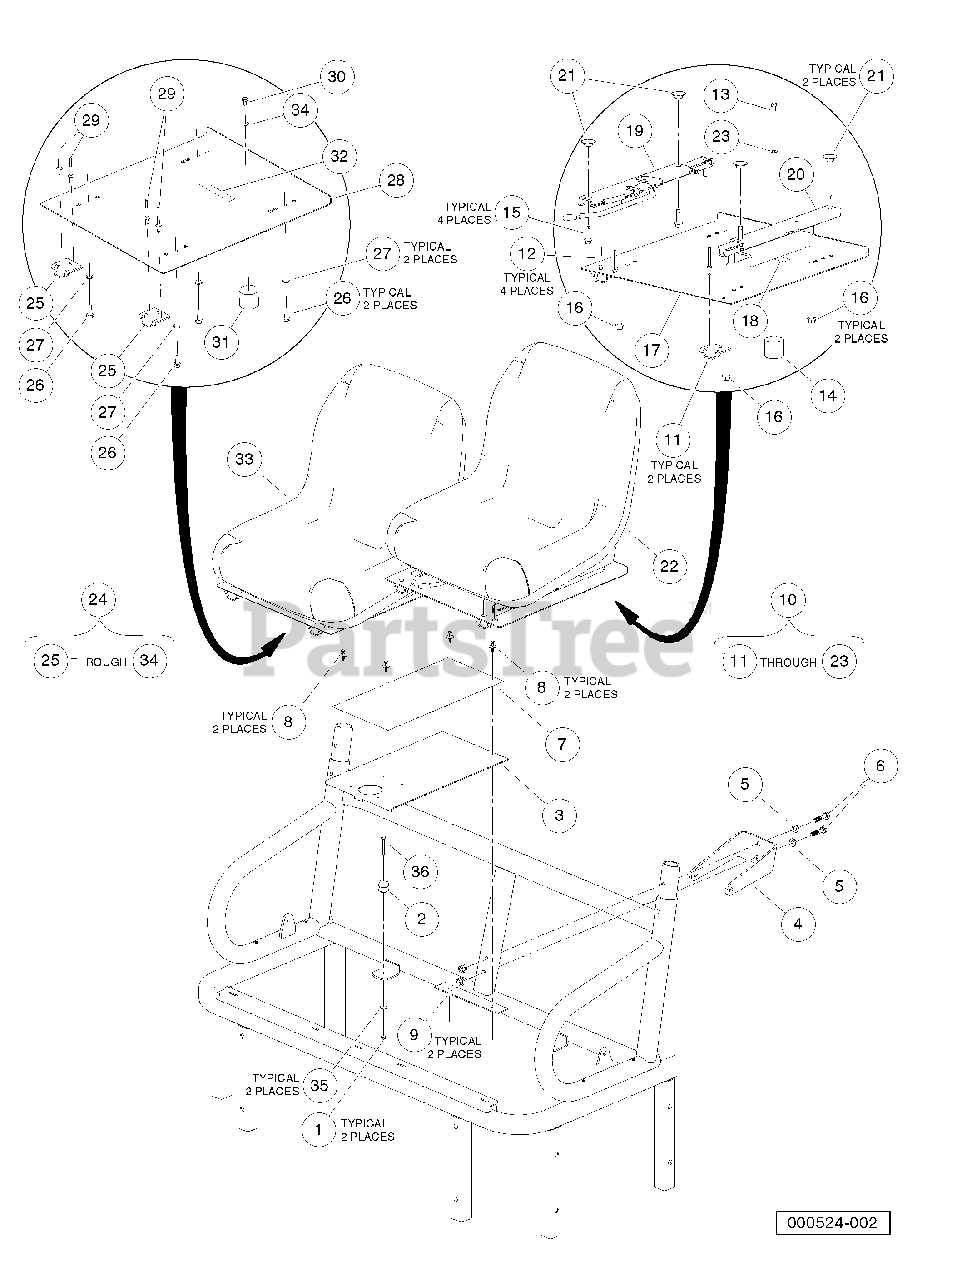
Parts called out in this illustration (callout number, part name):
1	Locknut, M6-1.00 Nylon Insert
2	Seat Holder Base
3	Pan, Center, Closeout
4	Bracket, Seatbelt, Bolt-On
5	Washer, Hard, M10, Zn-Ni/Blk
6	Bolt, M10 X 45, Zn-Ni
7	Cover, Center Console
8	Rivet, Removable, Tuflok 1/4"
9	Nut, Flanged, M10 x 1.5, Black
10	Asm, Bracket Seat, Adj, Blk
11	Hinge Plate
12	Rivet, 1/4 X .438 Blind
13	Screw, 6m-1.00 X 10mm Hex Head
14	Seat Holder Cup
15	Bolt, Flange Head, M8 X 30.0
16	Nut,m8,all Metal Lock
17	Pan, Seat, Driver Asm
18	Decal, Hot Surface Warning
19	Adjuster, Forward/Aft
20	Adjuster, Slider
21	Washer, Bell
22	Seat, Bucket, Black
23	Lockwasher, 1/4 Helical Split
24	Asm, Bracket Seat, Passenger, Blk
25	Hinge Plate
26	Screw, M8-125 X 22 Hex-Head
27	Lockwasher, 8mm Split
28	Pan, Seat, Passenger
29	Rivet, 1/4 X .438 Blind
30	Screw, 6m-1.00 X 10mm Hex Head
31	Seat Holder Cup
32	Decal, Hot Surface Warning
33	Seat, Bucket, Black
34	Lockwasher, 1/4 Helical Split
35	Washer, 1/4 Type A Narrow Flat
36	Bolt, M6 X 1 X 45
